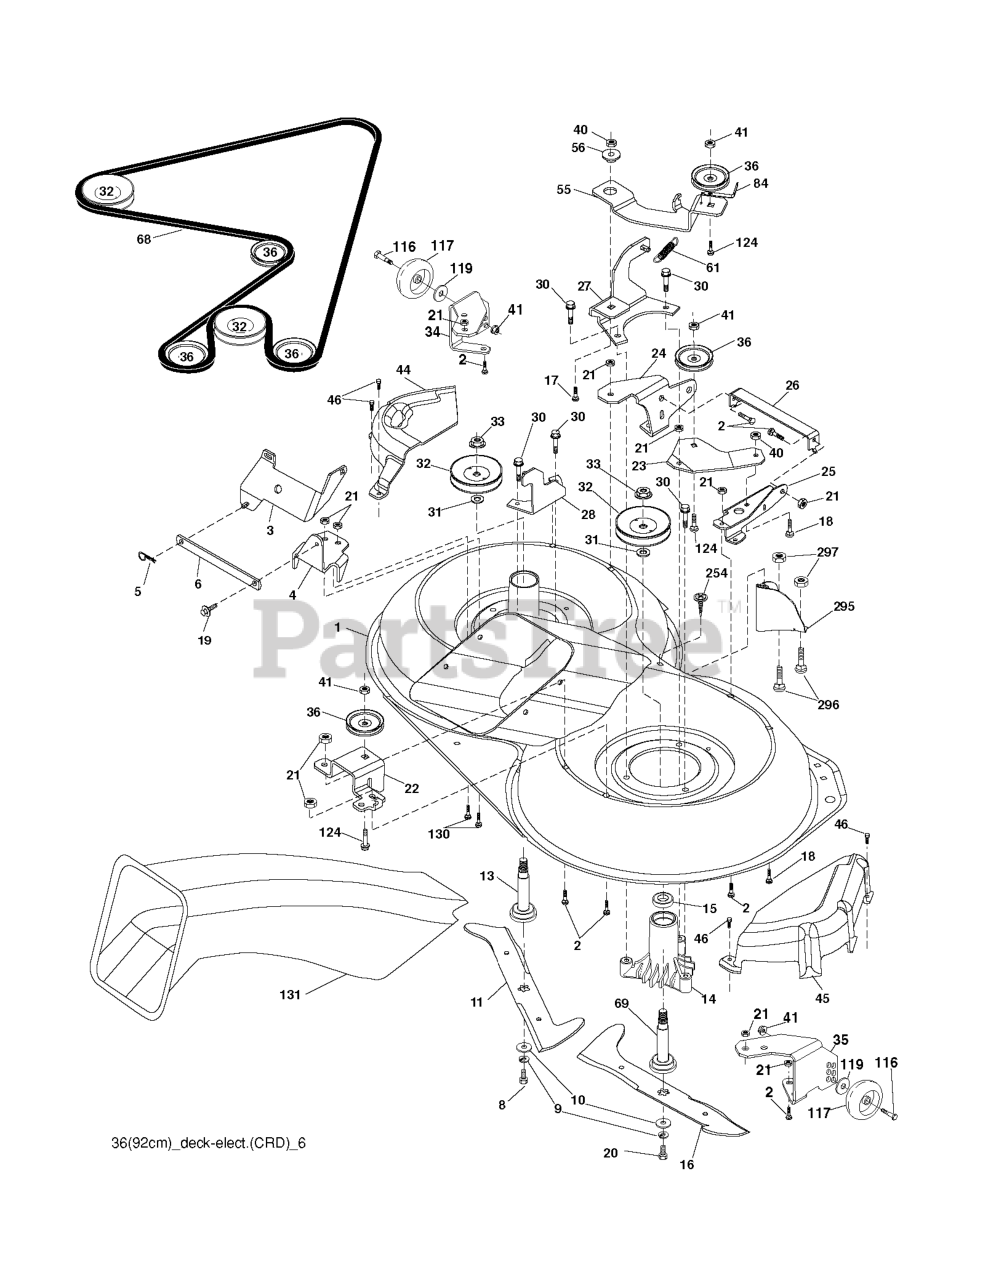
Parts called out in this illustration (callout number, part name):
2	RP BOLT 5/16-18 X3/4 ZN/YEL GR
5	RETAINER-SPRNG RB
6	BAR.SWAY.92.CRD
8	BOLT.3/8-24X1.25 GR8
9	LOCKWASHER
10	WASHER.BLADE
13	SHAFT ASM VENT
14	HOUSING.MANDREL.VENTED (MACHD)
17	BOLT.3/8-14X1.25
19	BOLT SHD 5/16-18
20	BOLT.3/8-24X1.25GR8. LHTHRD
21	LOCKNUT
26	SUPPORT
30	SCREW, WASHER HEAD
31	WASHER.SPACER.MANDREL
32	PULLEY MANDREL
33	NUT.FLANGE.LOCK.TOP
36	PULLEY.IDLER.4.25
41	NUT LOCK FLG 3/8-16 UNC
45	COVER.MANDREL.RH.CRD
46	SCREW.1/4-20X5/8
55	ARM.IDLER.92 CRD.2006
56	SPACER.RETAINER.MOWER
61	SPRING
68	BELT.DRIVE.92CM.CRD.2006
69	SHAFT.ASM.W/LWR.BRG.RH.THREAD
84	KEEPER, BELT IDLER
116	BOLT.SHOULDER.3/8-16X3-5/8.
117	RP WHEEL. GUAGE RALLY
119	WASHER
124	BOLT.3/8-16X1.50
130	BOLT.CARR.SQNK.5/16-18UNC.X3/4
131	CHUTE BAGGER
254	SCREW 3/8-16X1
296	BOLT
297	NUT CENTERLOCK
